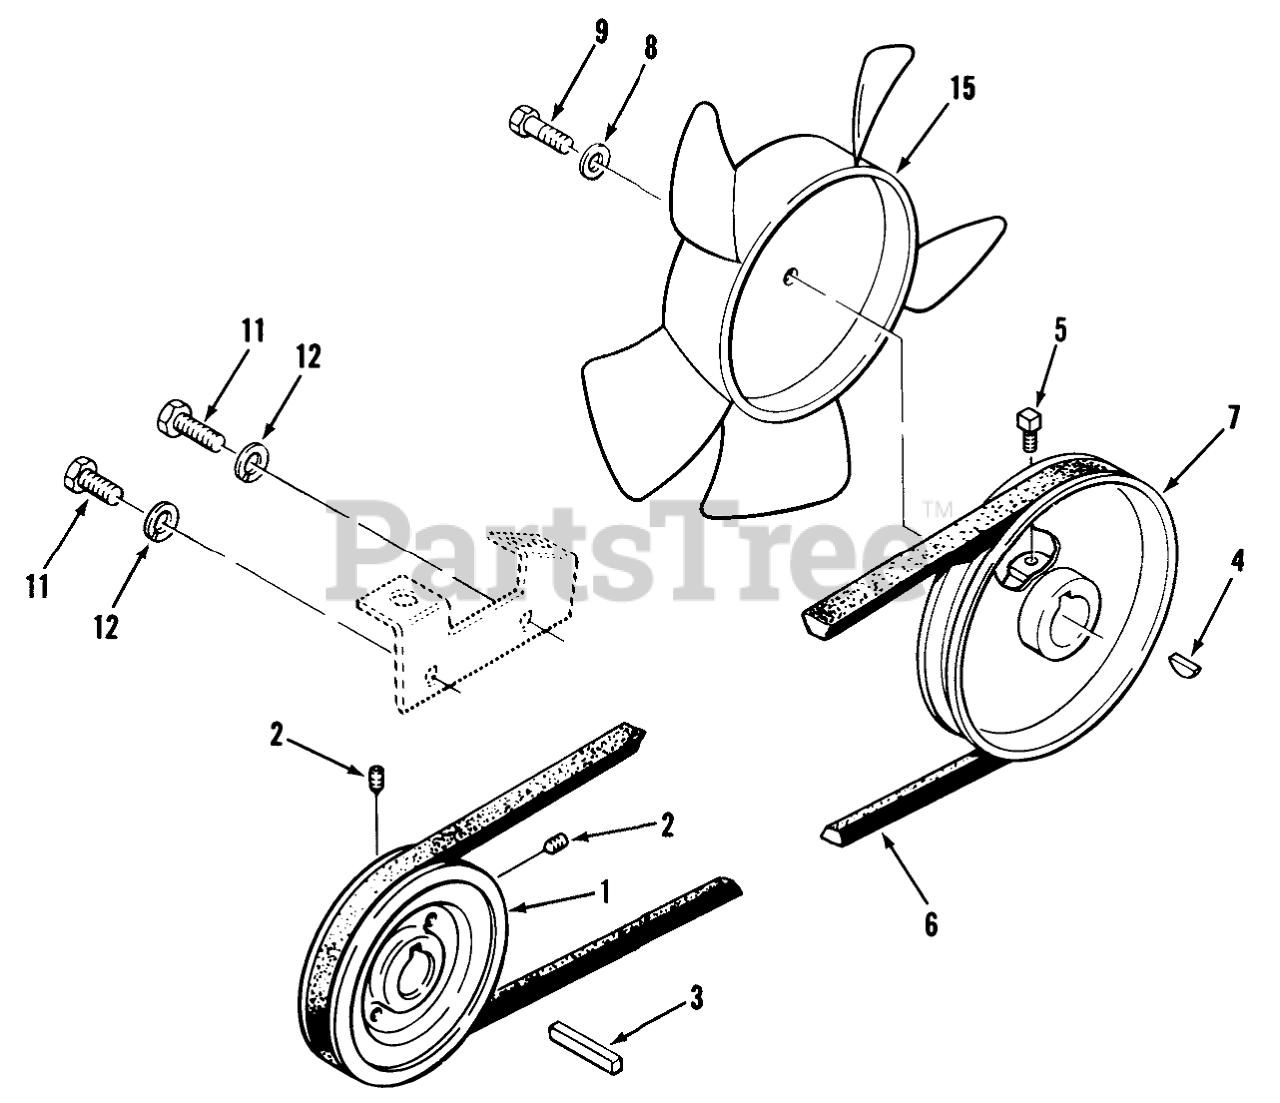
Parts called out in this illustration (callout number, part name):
1	PULLEY
2	Set Screw
4	KEY-WOODRUFF
5	Set Screw
6	BELT-V
7	PULLEY
8	WASHER
9	H H C S
11	SCREW-HH, LOCK
12	WASHER-PLAIN
15	NYLON FAN-L-CW
